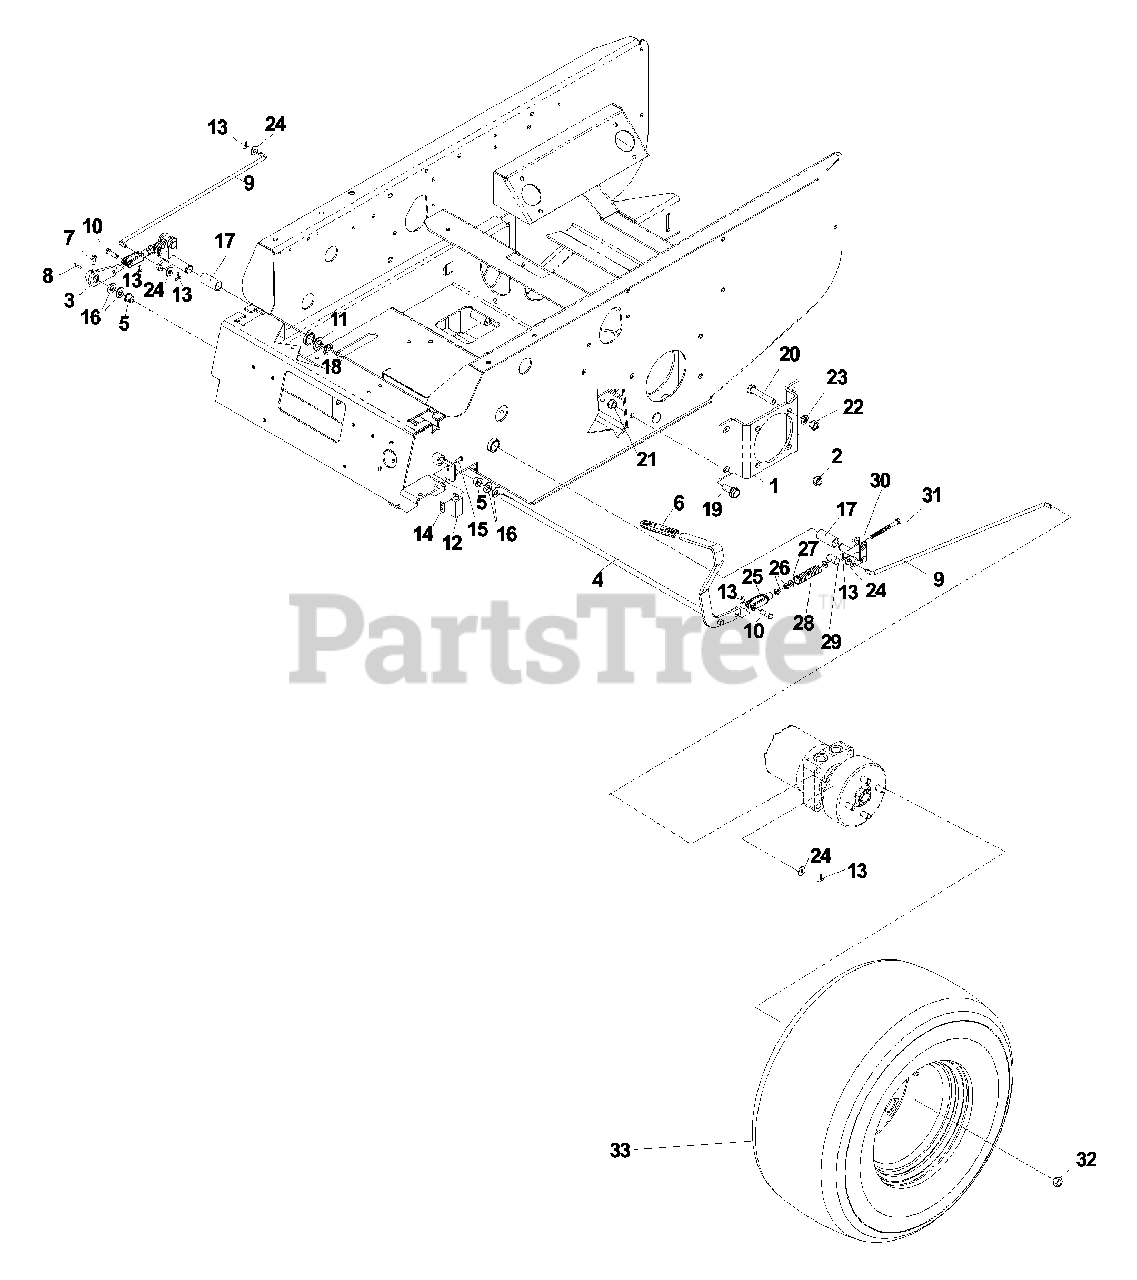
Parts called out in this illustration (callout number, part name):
1	Standoff, wheel motor
2	Nut, 1/2, lug
4	Brake lever
5	Bushing, bronze
6	Grip, park brake
7	Setscrew, 5/16-18 sq. x 5/8
8	Key, 1/8 sq. x 7/8
9	Brake linkage bar
10	Pin, clevis
11	Bushing, machine, 3/4
13	Pin, cotter
14	Plate, tapped
15	Screw, #10-24 x 5/8
16	Washer, 7/16, spring
17	Bearing, bronze
18	E-ring, 3/4
19	Bolt, 1/2-13 x 1 1/4, serrated washer
20	Bolt, 1/2-13 x 2 3/4
21	Nut, 1/2-13, nyloc
22	Nut, 1/2-13
23	Lockwasher, 1/2
24	Washer, 5/16
26	Nut, 3/8-24
27	Washer 3/8
29	Pin, trunion
31	Bolt, 3/8-24 x 4 1/2, special
32	Nut, 1/2, lug
33	Tire, rear, assembly
